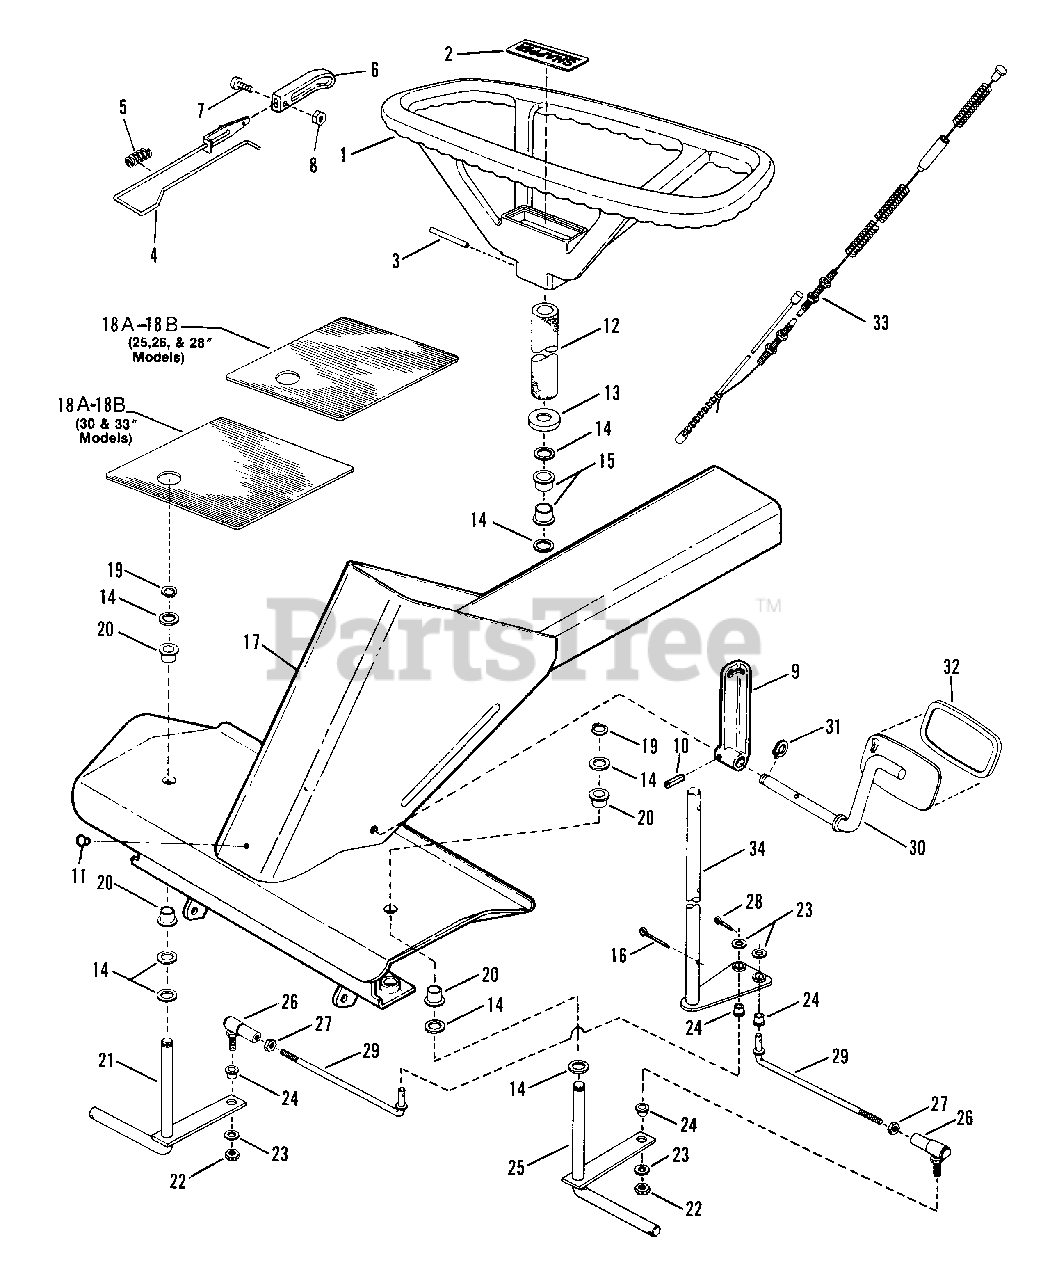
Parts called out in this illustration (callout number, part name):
1	STEERING WHEEL ASS'Y.
2	DECAL, Snapper
3	PIN, 1/4 x 1-1/2" Roll
4	BRACKET, Clutch/Brake
5	SPRING
6	KNOB
7	SCREW
8	NUT
9	ARM, Clutch/Brake
10	ROLL-PIN
11	PLUG
12	COVER, Steering Shaft (Foam)
13	COVER
14	WASHER, 3/4 Flat
15	BUSHING, 3/4", Steering Shaft
16	COTTER-PIN, 3/16 x 1-1/2"
17	FRAME, Front
18A	PAD, Foot, Right Side
18B	PAD, Foot, Left Side
18B	PAD, Foot, Right Side
19	RING, Retaining
20	BEARING
21	King Pin, R.H.
22	NUT, 3/8 - 24 Hex Lock
23	WASHER, 3/8" Flat
24	BUSHING
25	King Pin, L.H.
26	BALL JOINT, 3/8-24 Thread
27	NUT, 3/8 - 24 Hex
28	COTTER-PIN, 1/8-3/4"
29	TIE-ROD
30	PEDAL, Clutch/Brake
31	RING, 5/8" External Retaining
32	PAD, Clutch/Brake Pedal
33	CABLE, Clutch/Brake
34	SHAFT, Steering
